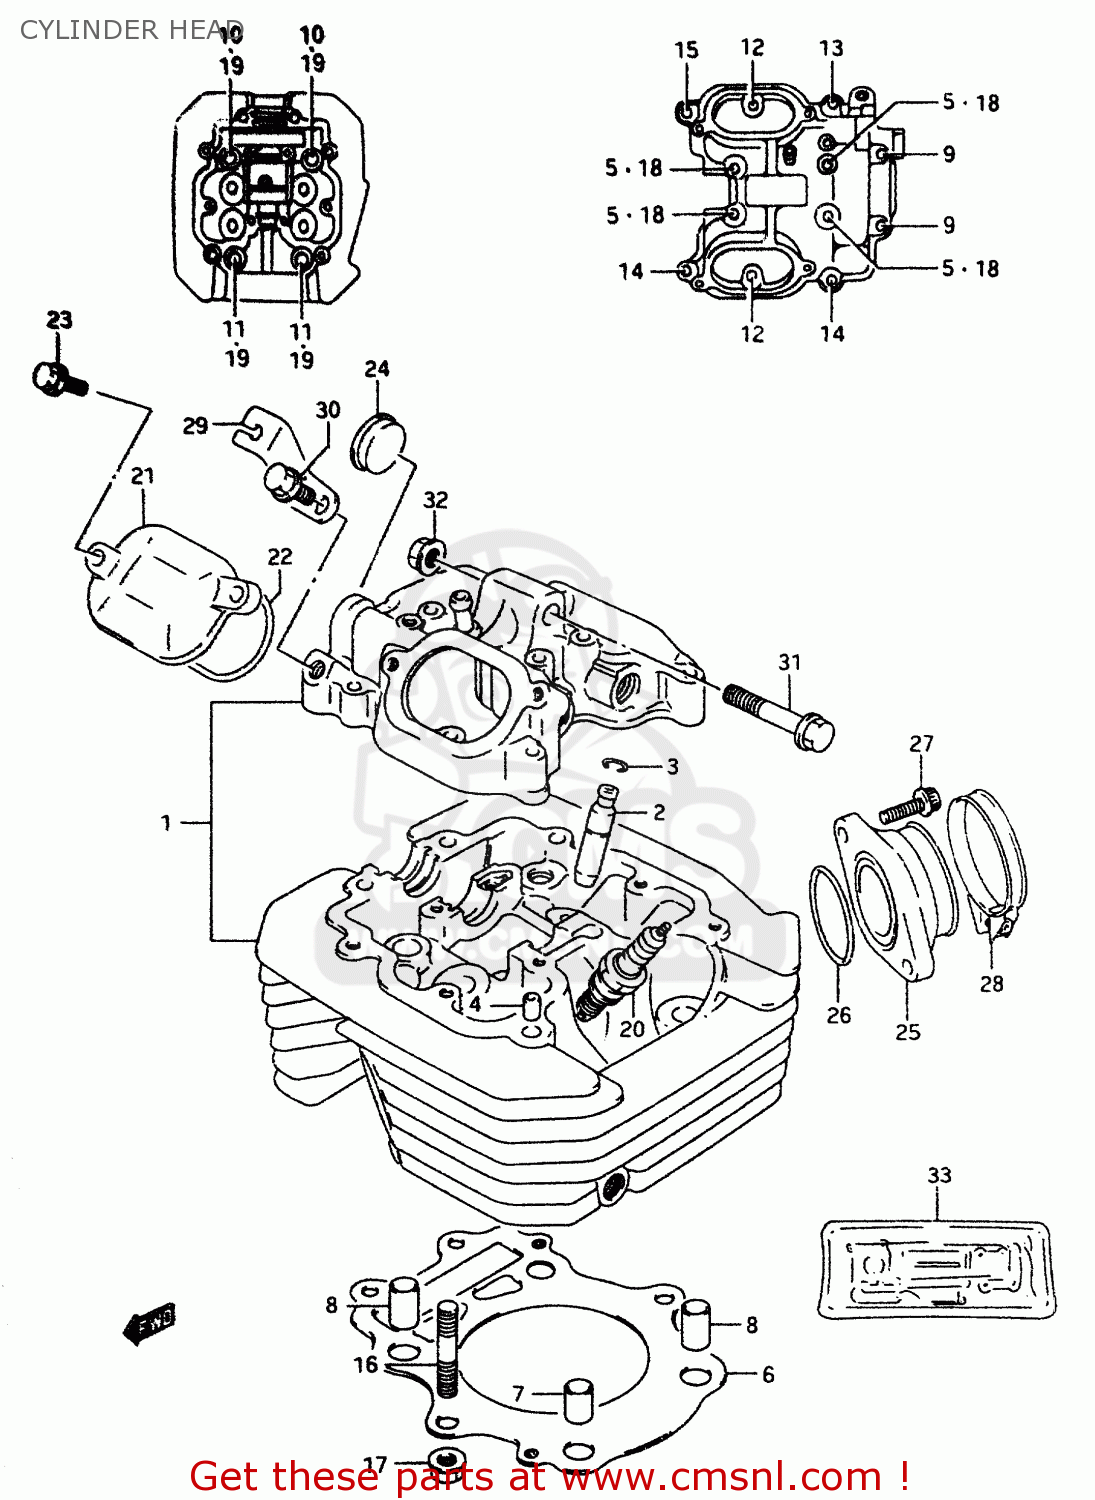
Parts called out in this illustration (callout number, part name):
1	HEAD ASSY,CYLINDER
2	GUIDE,VALVE
3	RING,SNAP
4	PIN(6.2X8X11)
5	BOLT(6X55)
6	GASKET,CYLINDER HEAD (NAS)
7	PIN
8	PIN(10.4X13X22)
9	BOLT(6X115)
10	BOLT(10X180)
11	BOLT(10X155)
12	BOLT
13	BOLT
14	BOLT(6X35)
15	BOLT(6X39)
16	BOLT,STUD
17	NUT
18	GASKET(5.8X13X1.2) (NAS)
19	WASHER (10.5X22X2.3)
20	PLUG,SPARK(CR9EK)
21	CAP,INSPECTION
22	O RING,INSPECTION CAP
23	BOLT
24	PLUG,OD:30
25	PIPE ASSY,INTAKE
26	O RING(D:2.4,ID:39.7)
27	BOLT
28	CLAMP
29	LEVER,DECOMP SHAFT RH
30	BOLT
31	BOLT(8X65)
32	NUT
33	GASKET SET (NAS)
